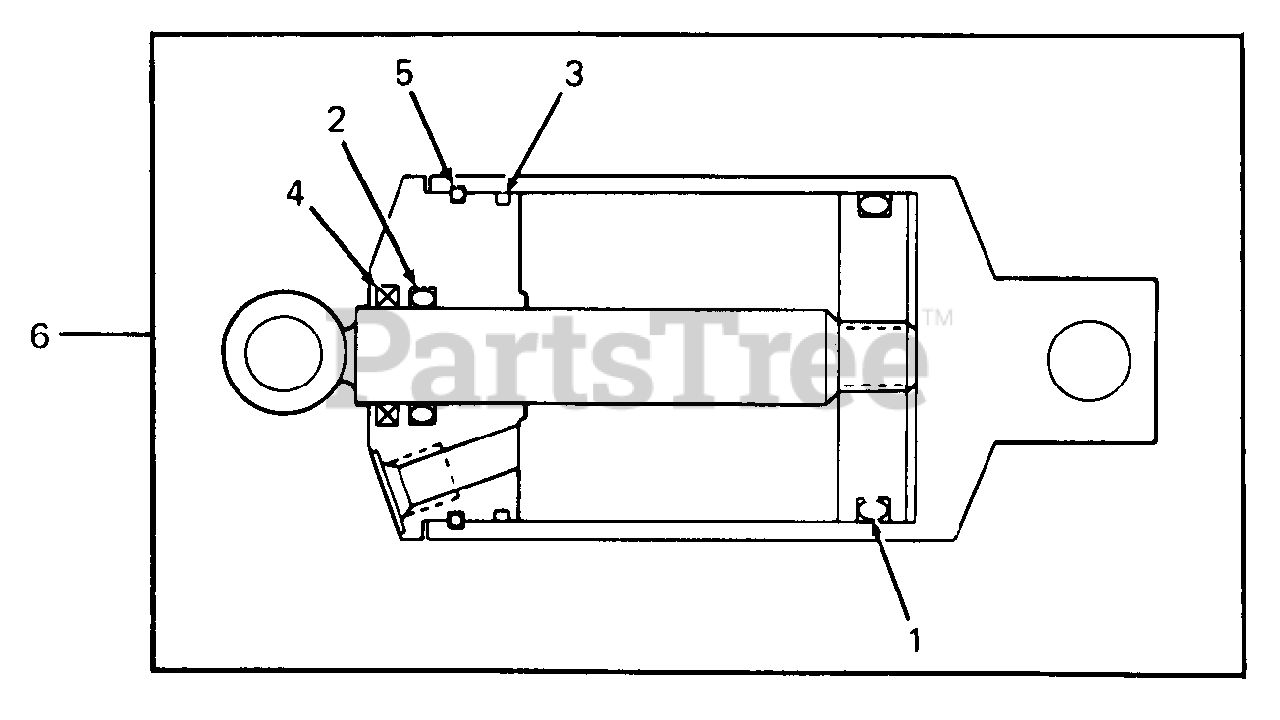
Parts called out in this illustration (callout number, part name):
4	Seal, Hydraulic Cylinder Piston Rod Wiper
5	Retainer, Hydraulic Cylinder Front Head
6	Cylinder, Hydraulic
